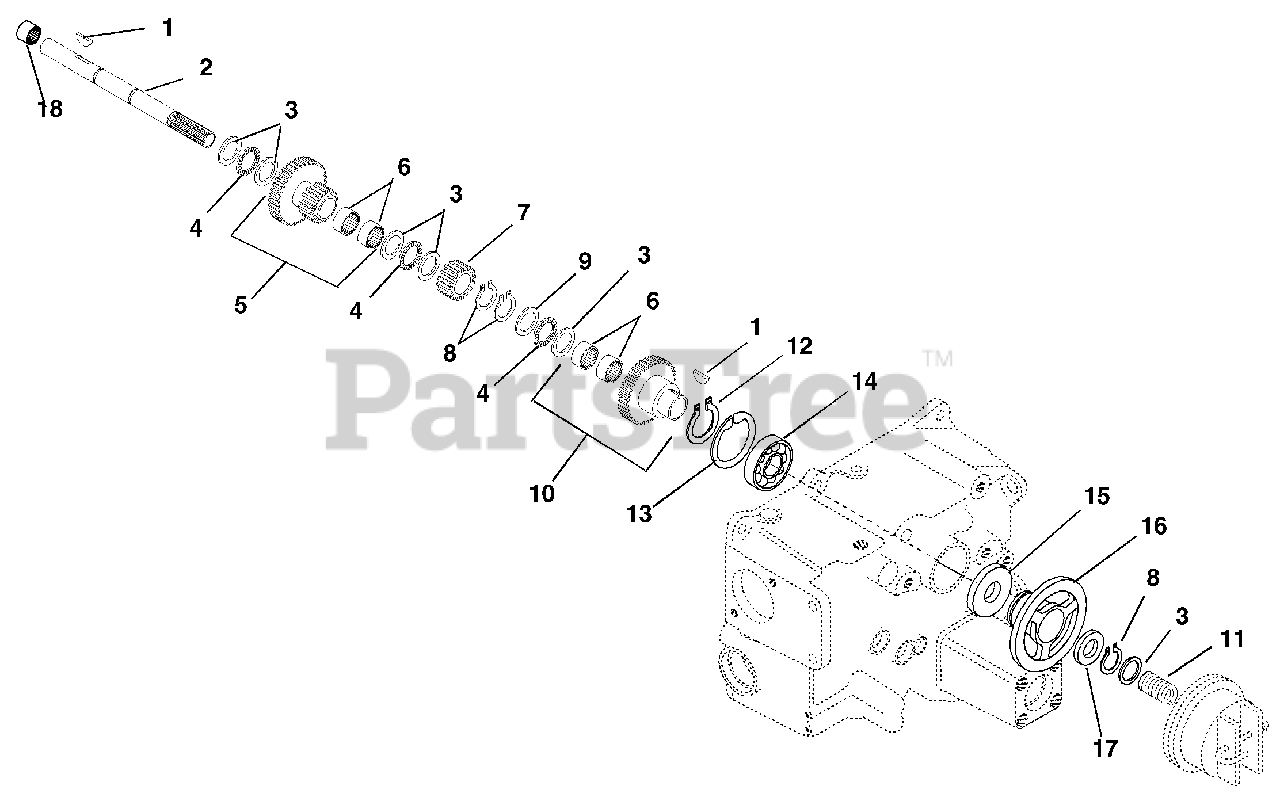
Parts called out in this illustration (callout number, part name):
1	Key-Woodruff .19 x .63
2	Shaft, Splined Reverse Clutch
3	Washer-Hardened-Thrust .76 x 1.23 x .031
4	Bearing-Needle Thrust .75 x 1.24 x .078
5	Gear,Idler Assembly
6	Bearing-Roller .75 x 1.0 x .50
7	Gear,10 Diametral Pitch 16 Teeth x .75
8	Ring-Retaining-Internal .75 x .042
9	Washer-Thrust-Hardened .75 x 1.24 x .062
10	Assembly, Reverse Gear and Bearing
11	Spring-Compression .09 x .80 x 1.00
12	Ring-Retaining-External 1.82 x .062
13	Ring-Retaining-Internal 3.52 x .11
14	Bearing-Ball 1.97 x 3.14 x .63
15	Seal 2.25 x 3.00 x .38
16	Hub,Clutch
17	Seal .75 x 1.63 x .25
18	Bearing-Needle .75 x 1.00 x .75
